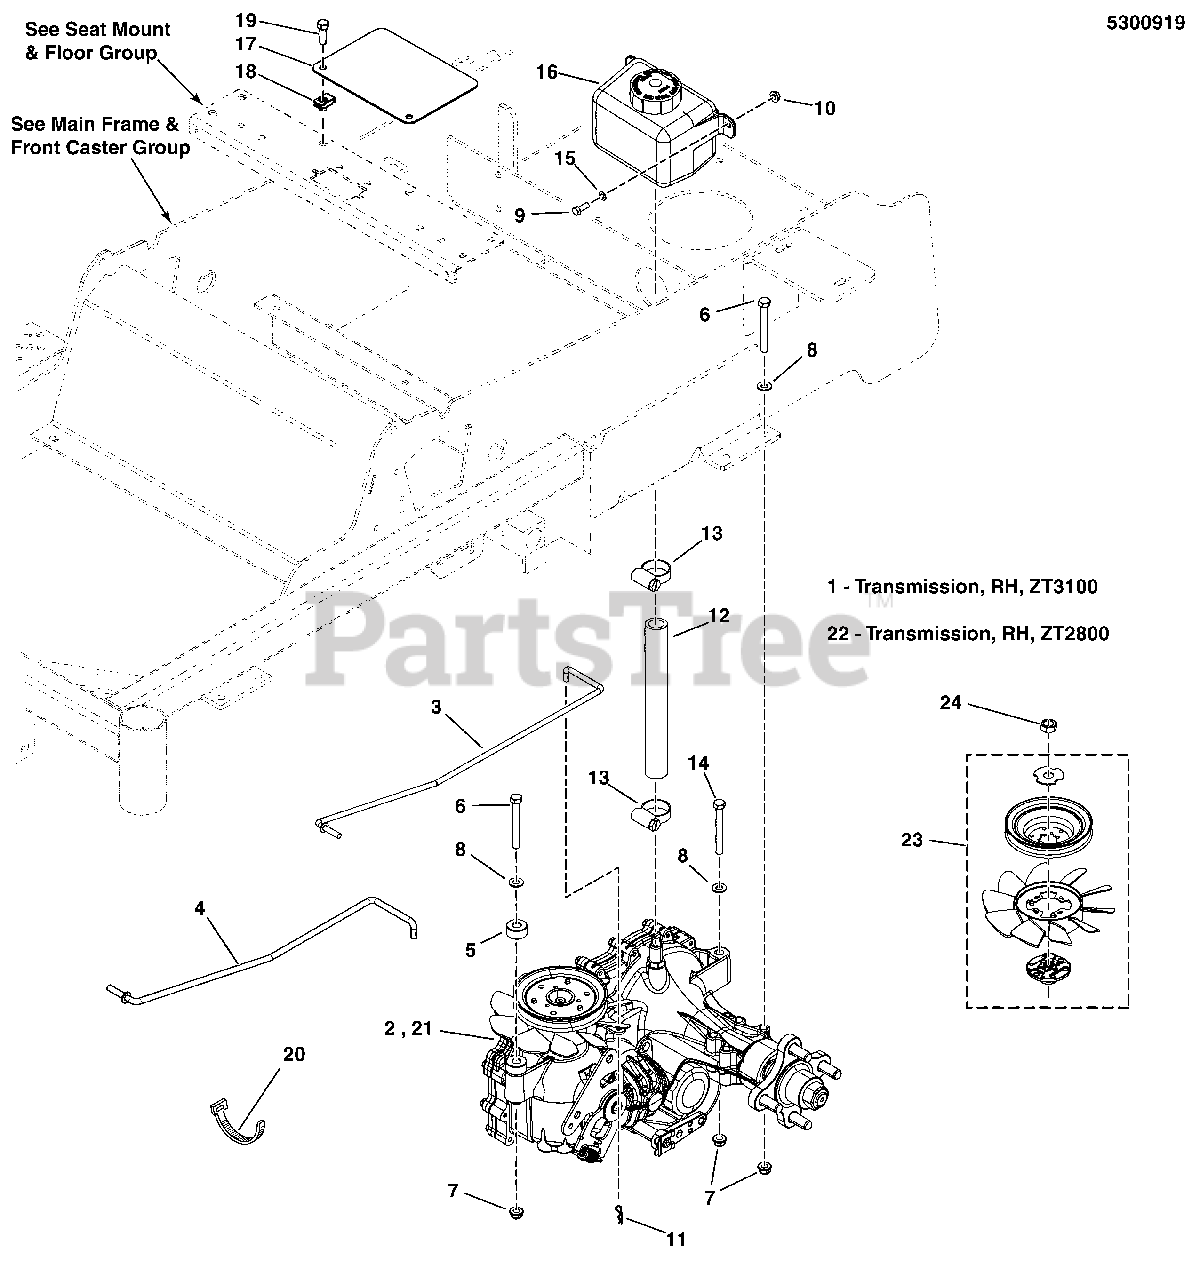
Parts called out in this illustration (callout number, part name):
1	TRANSMISSION, RH, HYDRO-GEAR
2	TRANSMISSION, LH, HYDRO-GEAR
3	ROD, DUMP CONTROL, LH
4	ROD, DUMP CONTROL, RH
5	SPACER, .39 X .75 X .50
6	BOLT, 5/16-18 X 2-3/4, GD 5, YZ
7	NUT, 5/16-18 HEX NYLOCK FLANGE
8	WASHER, 5/16 SAE
9	BOLT, 1/4-20 X 3/4 GD5 YZ
10	NUT, 1/4-20 HEX NYLOCK FLANGE (5025391)
11	PIN, HAIR, .0585 X 1-1/8, 1/4 EYE, YZ
12	HOSE, 1/2" PUSH-ON, 2.5" LONG
13	CLAMP, HOSE, .75 FREE DIA.
14	BOLT, 5/16-18 X 2-1/4" GD5 YZ
15	WASHER, 1/4 SAE (5025154)
16	TANK, OIL, 350ML WITH CAP
17	PLATE, BELT GUARD - BLACK
18	BODY CLIP, 5/16-18-7GA MATERIAL
19	BOLT, 5/16-18 X 1 GD5 YZ
20	TIE, SELF-LOCKING, 12"
21	TRANSAXLE, ZT2800,LH, ZK-KMEE-3L7C-1XLX
22	TRANSAXLE, ZT2800, RH, ZK-GMEE-3L7B-1XLX
23	KIT, FAN AND PULLEY (72134)
24	NUT, ZT5400
